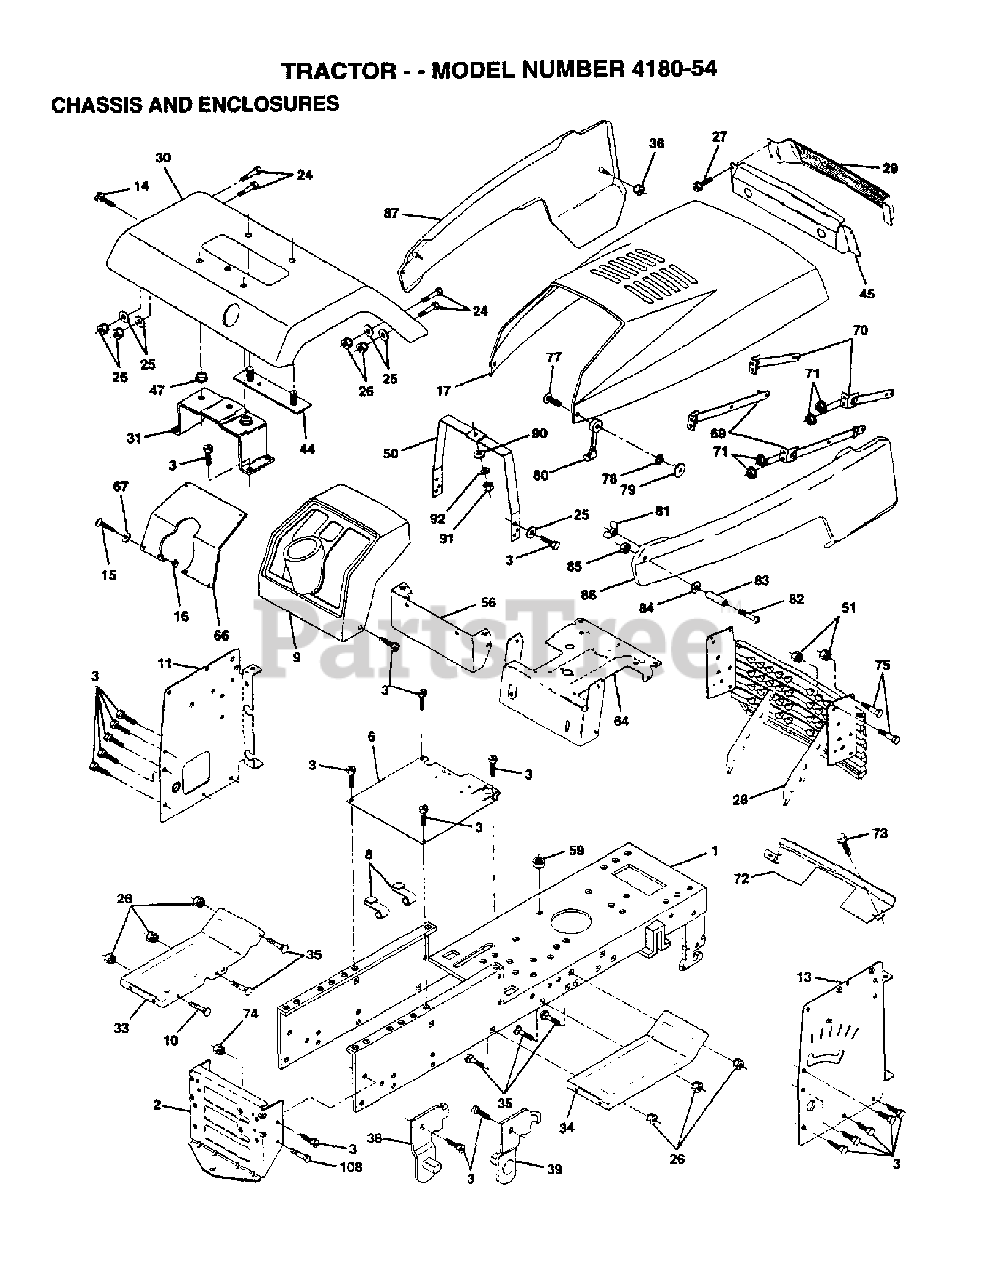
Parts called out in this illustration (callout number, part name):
2	DRAW BAR
8	CLIP,INSULATOR
14	SCREW LT
17	Poulan TBD
25	WASHER
26	NUT
30	Poulan TBD
31	FENDER BRKT
33	Poulan TBD
34	Poulan TBD
36	PAL NUT LT
38	BRACKET LH PIVOT
39	BRACKET RH PIVOT
44	STRAP-FENDER YT
47	NUT-PUSH YT
50	DASH SUPT YP
51	NUT.CROWNLOCK.1/4
56	DASH EXT PNT
67	WASHER
71	NUT.HEX.KEPS.1/4-20
72	Poulan TBD
73	SCREW CRT
74	LOCKNUT
75	Bolt
77	SCREW
78	LOCKWASHER
79	NUT.WELD
80	LATCH.HOOD.
81	WING NUT
82	SCREW
83	SPACER LT
84	WASHER
85	NUT **
86	Poulan TBD
87	Poulan TBD
90	WASHER PM
91	NUT
92	LOCKWASHER
